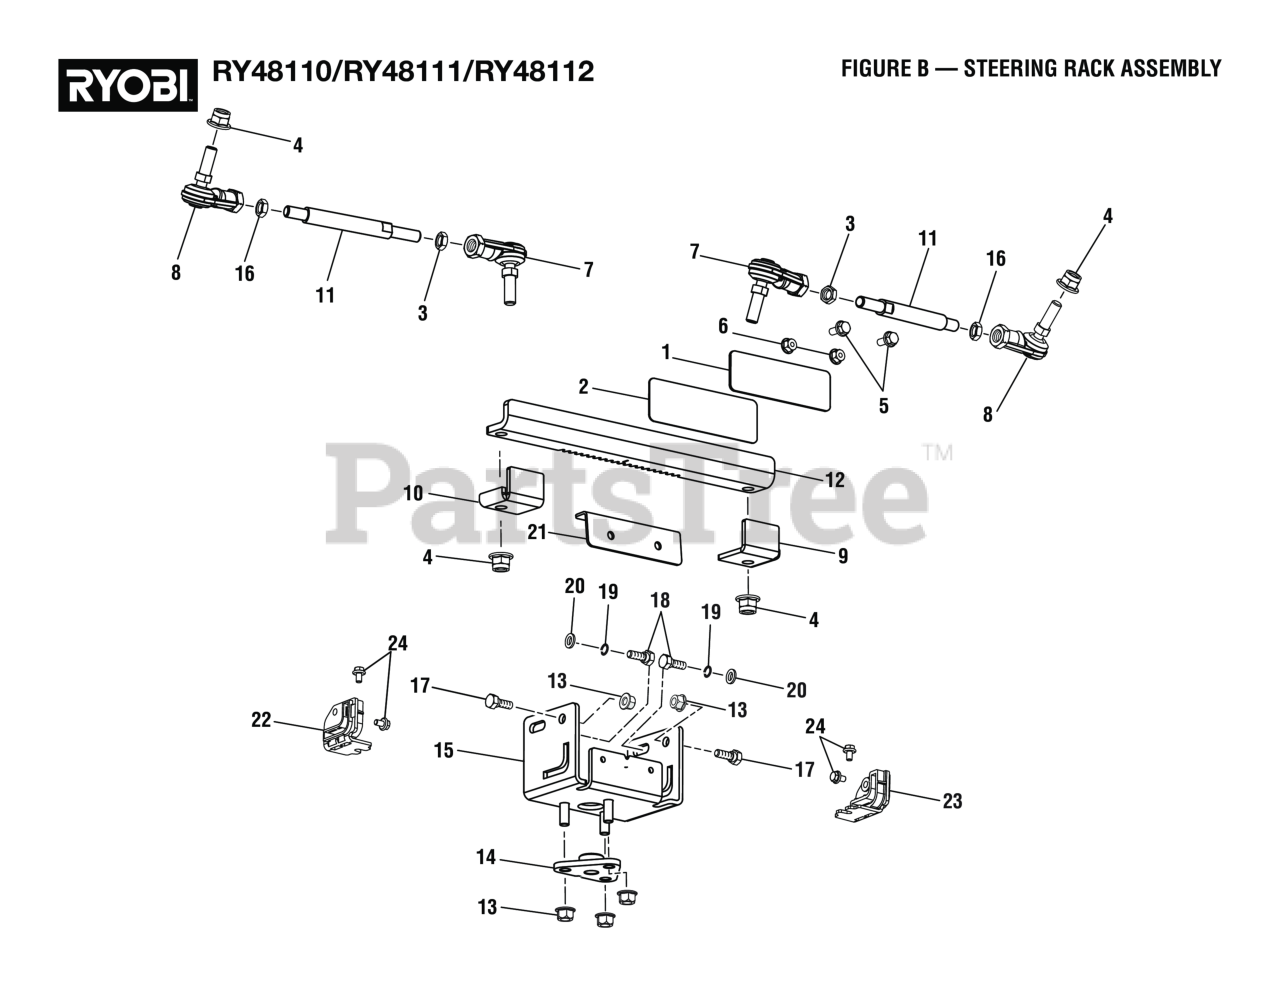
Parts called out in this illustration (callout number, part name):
1	Steel Pad
2	Shim Steering Rack
3	Nut (M10)
4	Flange Lock Nut (M10 x 1.25 mm)
5	Flange Bolt (M6 x 14 mm, Hex Hd.)
6	Flange Nut (M6)
8	Rod End 2
9	Left Rack Limiter
10	Right Rack Limiter
12	Steering Rack
13	Flange Nut (M8) (For Drive Motor Controller V)
14	Steering Shaft Seat
15	Seat Bracket
16	Hex Nut (M10 x 1.25 mm, Left Hand)
17	Hex Bolt (M8 x 25 mm)
18	Bolt (M8 x 25 mm, Hex Hd.)
19	Lock Washer (OD9.8 x ID8.5 x 5t)
20	Washer (OD16 x ID8.4 x 1.6t)
21	Rack Shim Limiter
22	Rack Bushing (Right)
23	Rack Bushing (Left)
24	Bolt (M5 x 8 mm, Hex Flange Hd.)
